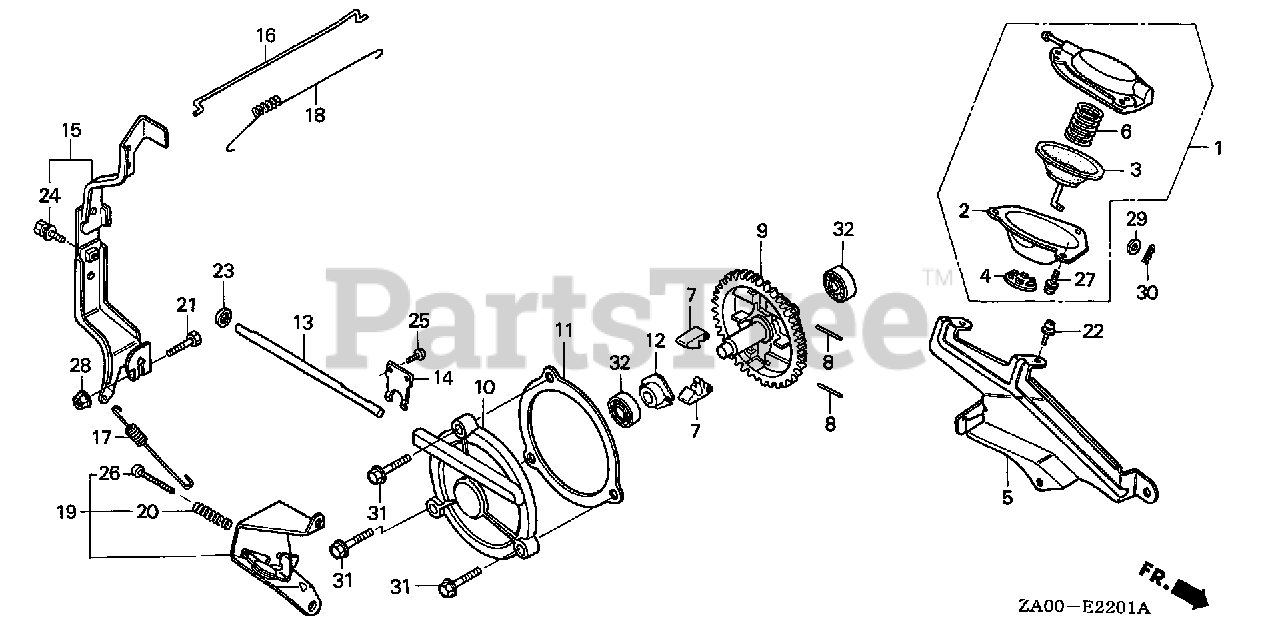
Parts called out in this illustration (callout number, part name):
1	DIAPHRAGM ASSY.
2	COVER, DIAPHRAGM
4	BUSH, DIAPHRAGM COVER
5	STAY ASSY., DIAPHRAGM
6	SPRING, COIL
7	WEIGHT, GOVERNOR
8	PIN, GOVERNOR WEIGHT
9	SHAFT, GOVERNOR
10	COVER, GOVERNOR
11	GASKET, GOVERNOR COVER
12	SLIDER, GOVERNOR
13	SHAFT, GOVERNOR ARM
14	FORK, GOVERNOR
15	ARM, GOVERNOR
16	ROD, GOVERNOR
17	SPRING, GOVERNOR
18	SPRING, THROTTLE RETURN
20	SPRING, CONTROL ADJUSTING
21	BOLT, GOVERNOR ARM
22	SCREW-WASHER (5X8)
23	OIL SEAL (8X14X5)
24	BOLT-WASHER (6X12)
25	SCREW, PAN (3X8)
26	SCREW, PAN (5X28)
27	SCREW-WASHER (4X8)
28	NUT, FLANGE (6MM)
29	WASHER, PLAIN (4MM)
30	PIN, LOCK (4MM)
31	BOLT, FLANGE (6X25)
32	BEARING, RADIAL BALL (6000)
